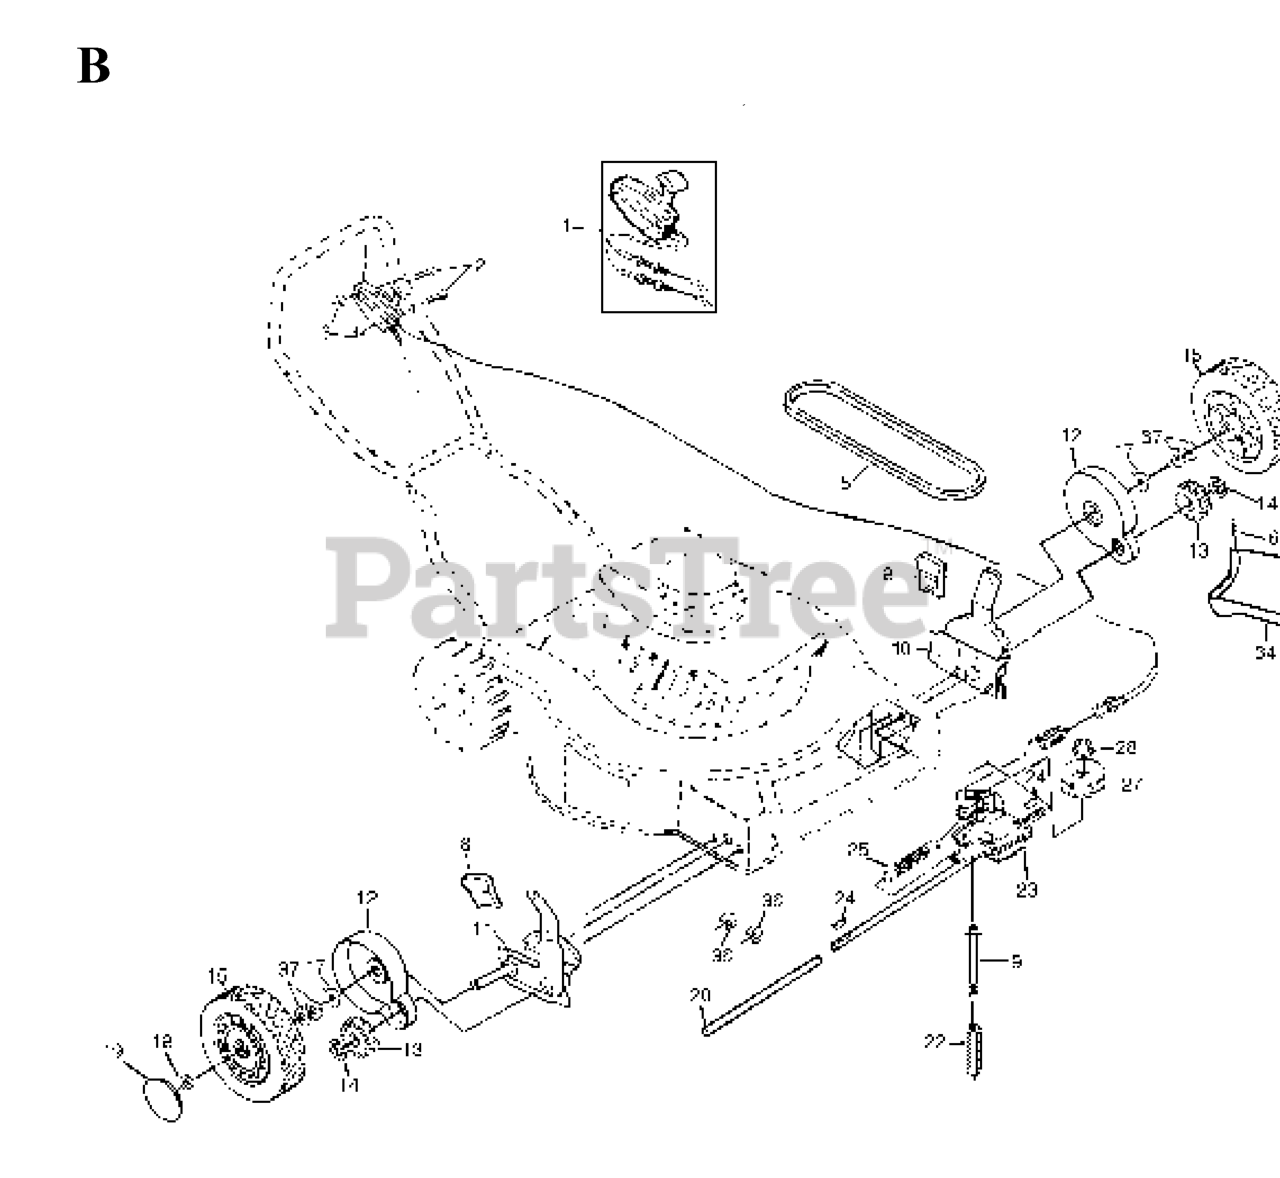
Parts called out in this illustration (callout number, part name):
1	DRIVE CONTROL
2	SCREW 1/4-20 X 2.12
3	NUT
5	BELT THERM .32
6	TAPPING SCREW
8	SELECTOR KNOB
9	SPRING RETAINER
10	WHEEL ADJUSTER ASSY (LEFT)
11	WHEEL ADJUSTER KIT RH
12	DUST SHROUD PM
13	PINION GEAR
14	E-RING 7/16 RE
15	WHEEL & TIRE 8 X 2
17	WASHER FLUT
18	HEX FLANGE LOCKNT
20	DRV SHAFT TUBE PM
22	SPRING.EXTENSION
23	RP.GEAR HOUSING
24	HI PRO KEY
27	PULLEY
28	FLANGED LOCKNUT 3/8-16 ZINC
34	COVER DRIVE
36	NUT
37	WAVE WASHER
